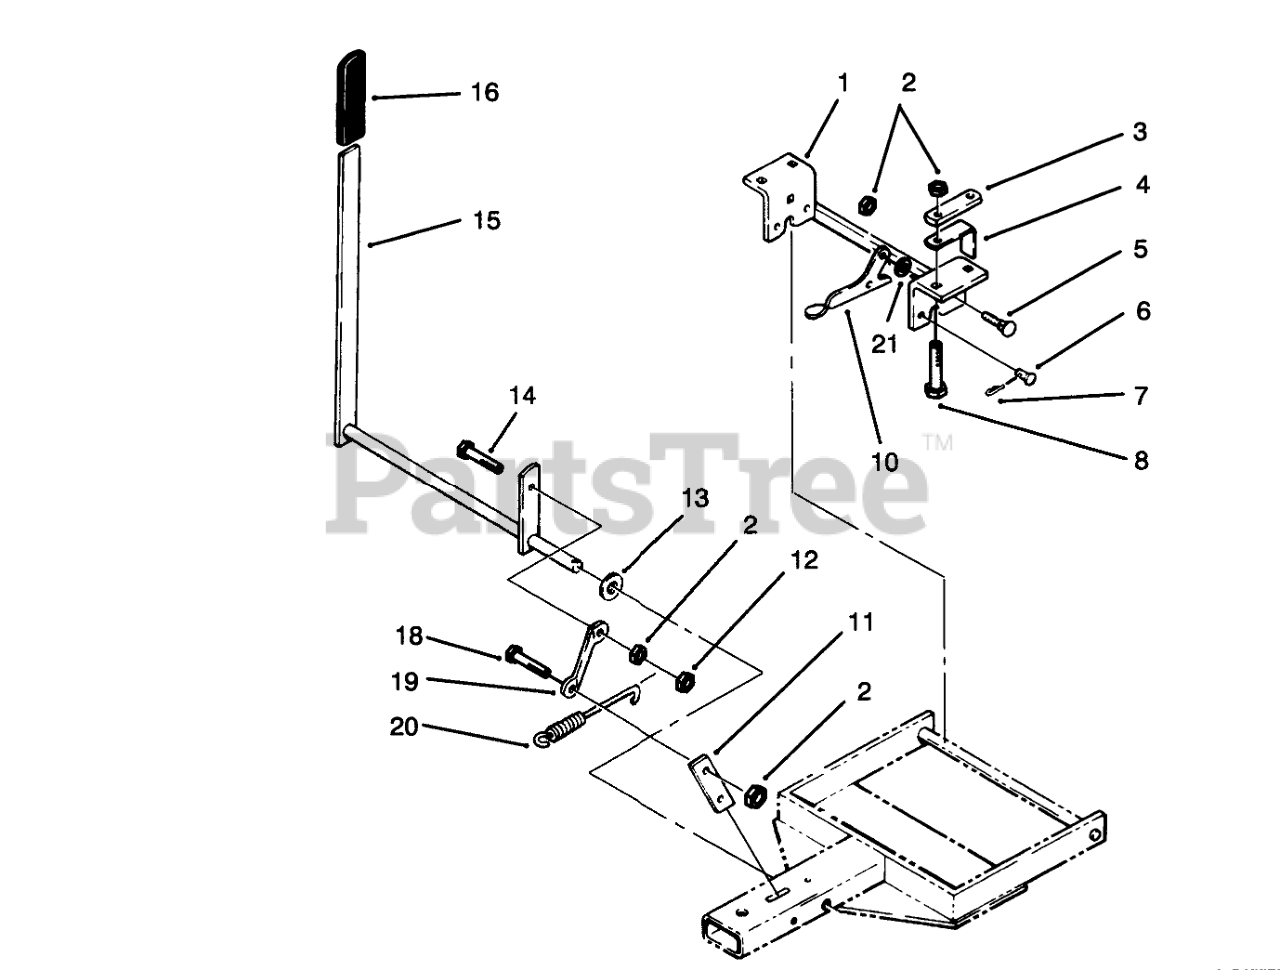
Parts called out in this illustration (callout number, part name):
1	Bracket
2	NUT-LOCK, NI
3	BRACKET-REAR LINK MOUNTING
4	SPACER-BRACKET
5	BOLT-CARR
6	PIN-CLEVIS
7	Hairpin
8	SCREW-CARR
10	PLATE-LATCHING
11	Latch
12	NUT-HEX, JAM
13	WASHER-FLAT
14	SCREW-HH
15	ASS'Y-LATCH HANDL R
16	GRIP
18	SCREW-HH
19	Latch Link
20	SPRING
21	WASHER-FLAT
